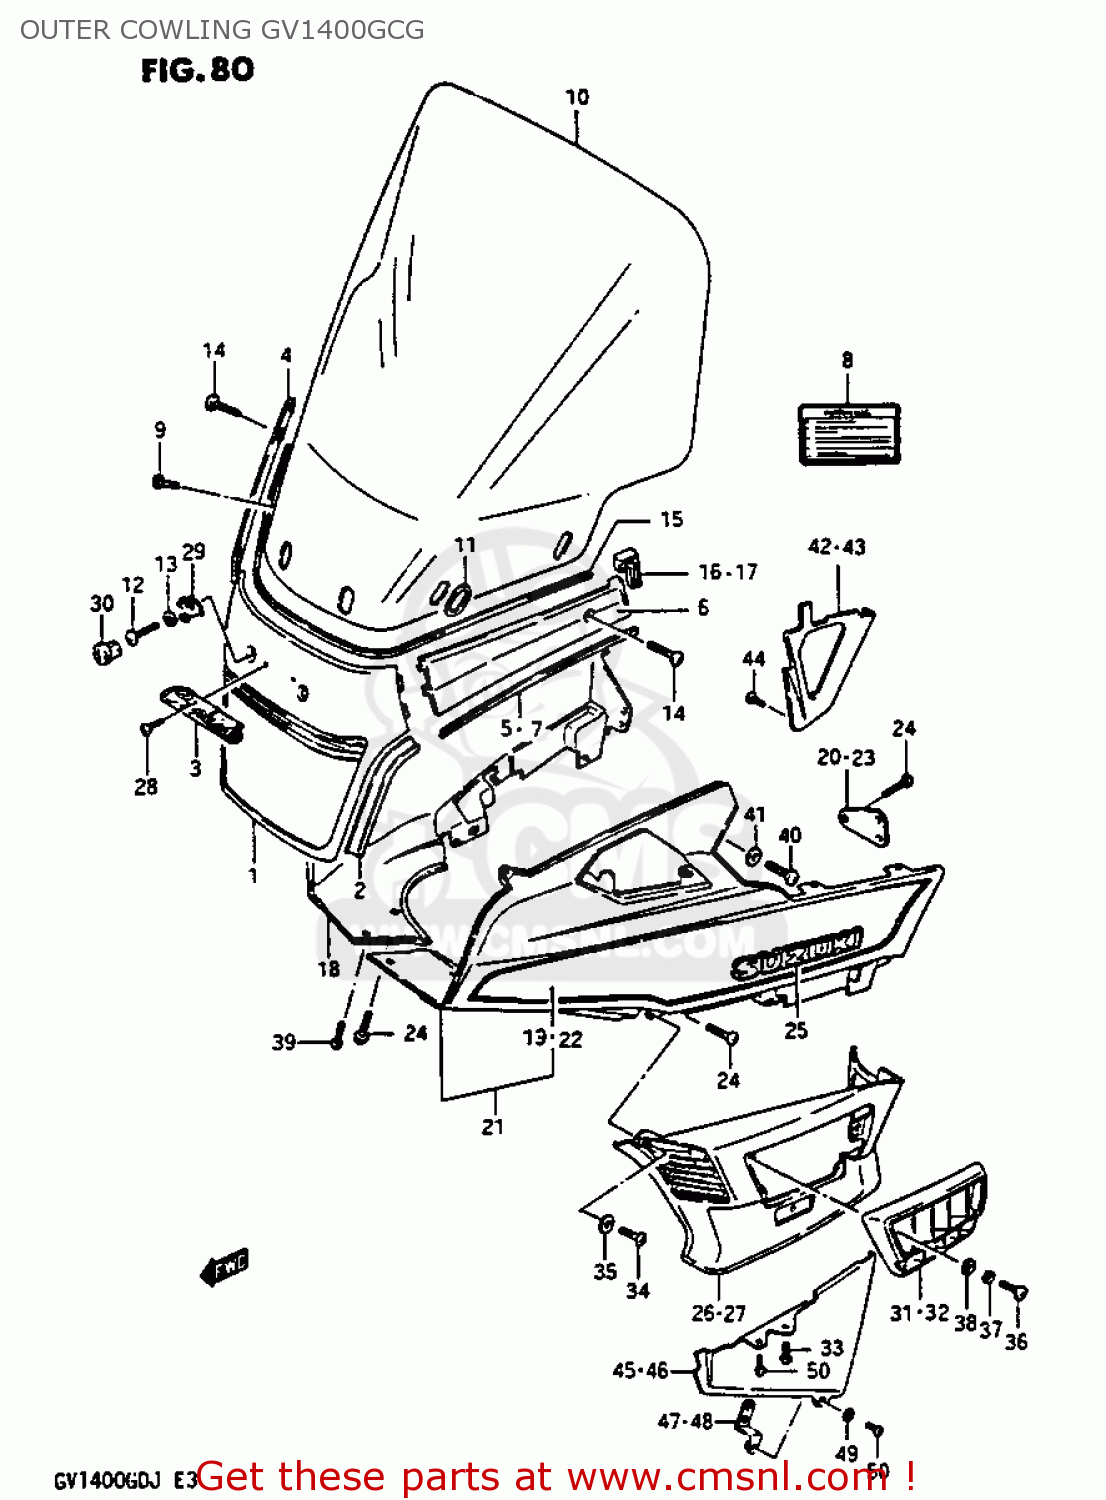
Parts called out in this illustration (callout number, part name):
1	COVER,COWLING,FRONT,CENTER
2	MOLDING,FRONT COVER,LOWER
3	EMBLEM,COWLING,FRONT
4	COVER,COWLING,FRONT,RIGHT
5	MOLDING,FRONT COVER SIDE
6	COVER,COWLING,FRONT,LEFT
7	MOLDING,FRONT COVER SIDE
8	LABEL (WARNING SCREEN)
9	SCREW
10	SCREEN ASSY,COWLING
11	WASHER,SCREEN
12	SCREW
13	WASHER
14	SCREW
15	SEAL,FRONT COVER,CENTER
16	CAP,COWLING FRONT COVER END
17	CAP,COWL FR COVER END,L
18	BODY,COWLING,RIGHT
19	TAPE SET,COWLING
20	BRACKET,COWLING BODY,RIGHT
21	BODY,COWLING,LEFT
22	TAPE SET,COWLING
23	BRACKET,COWLING BODY,RIGHT
24	SCREW
25	EMBLEM,COWLING SIDE,LEFT
26	COVER ASSEMBLY,COWLING
27	COVER ASSEMBLY,COWLING SIDE,LEFT
28	SCREW
29	PLATE,FRONT COVER LOCK
30	CAP,FR COVER
31	LOUVER,SIDE COVER,RIGHT
32	LOUVER,SIDE COVER,LEFT
33	SCREW (M6X1X16)
34	SCREW
35	WASHER (4.3X13X0.80)
36	SCREW 4X16
37	LOCK WASHER
38	WASHER
39	SCREW
40	SCREW
41	WASHER
42	UNDER COVER, FRAME
43	COVER,COVER FRAME,UPPER
44	SCREW
45	COVER,COWLING SIDE,LOWER
46	COVER,COWLING SIDE,LOWER
47	BRACKET,COWLING SIDE,LOWER
48	BRACKET,COWLING SIDE,LOWER
49	WASHER
50	SCREW 5X10
